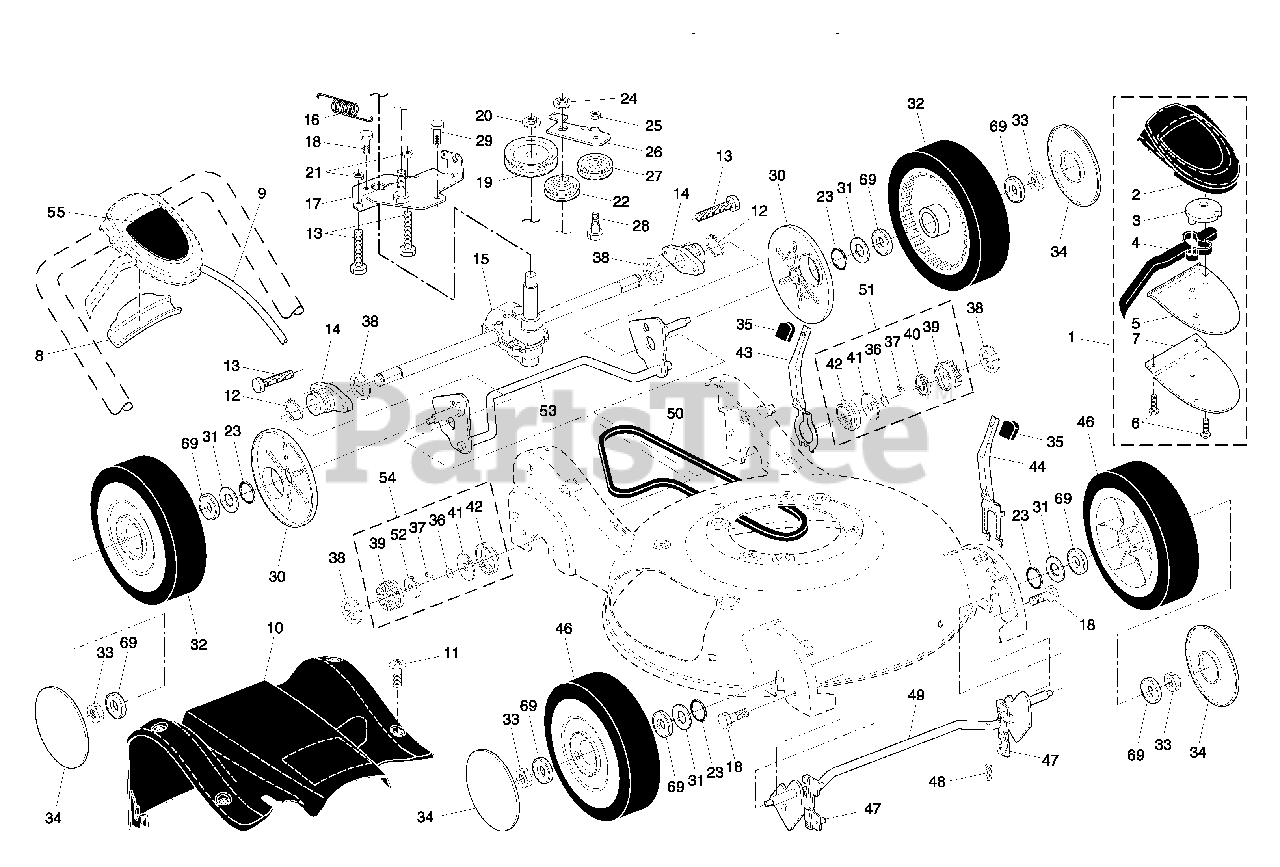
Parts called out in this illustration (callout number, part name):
1	Drive Control Assembly, Complete
2	Cover, Drive Control, Top
3	Pulley, Drive Control
4	Lever, Drive Control (blue)
5	Cover, Drive Control, Bottom
6	Screw, Torx Head #8-5/8
7	Bracket, Mounting, Drive Control
8	Cap, Drive Control, Bottom
9	Cable, Drive Control
10	Cover Assembly, Drive
11	Screw
12	Ring, Retaining
13	Screw
14	Bearing / Axle Support
15	Gear Case Assembly
16	Spring, Return
17	Bracket, Gear Case / Drive Pulley
19	Pulley, Drive
20	Nut, Hex, Flangelock
21	Nut, Hex
22	Pulley Assembly, V-Groove
23	O-Ring
24	Nut, Hex, Flangelock
25	Nut, Hex, Lock
26	Idler Arm
27	Pulley, Idler
28	Bolt, Hex Head, Shoulder
29	Screw 1/4-20 x 1/16
30	Cover, Dust, Wheel
31	Washer, Flat 3/8
32	Wheel Assembly, Rear 9 x 2-1/4
33	Nut, Hex
34	Hubcap
36	Spring, Torsion
40	Retainer, Drive, LH
41	Disc, Drive
42	Seal, Friction
43	Lever, Selector, Wheel Height, Rear
44	Lever, Selector, Wheel Height, Front
46	Wheel Assembly, Front 9 x 2-1/4
47	Bushing, Front Axle
48	Retainer, Hairpin Cotter
49	Torque Shaft Assembly, Front
50	Belt, Drive
51	Pinion Assembly, LH
52	Retainer, Drive, RH
53	Rear Axle Assembly
54	Pinion Assembly, RH
55	Decal, Drive Control
69	Bearing, Ball (Wheel)
